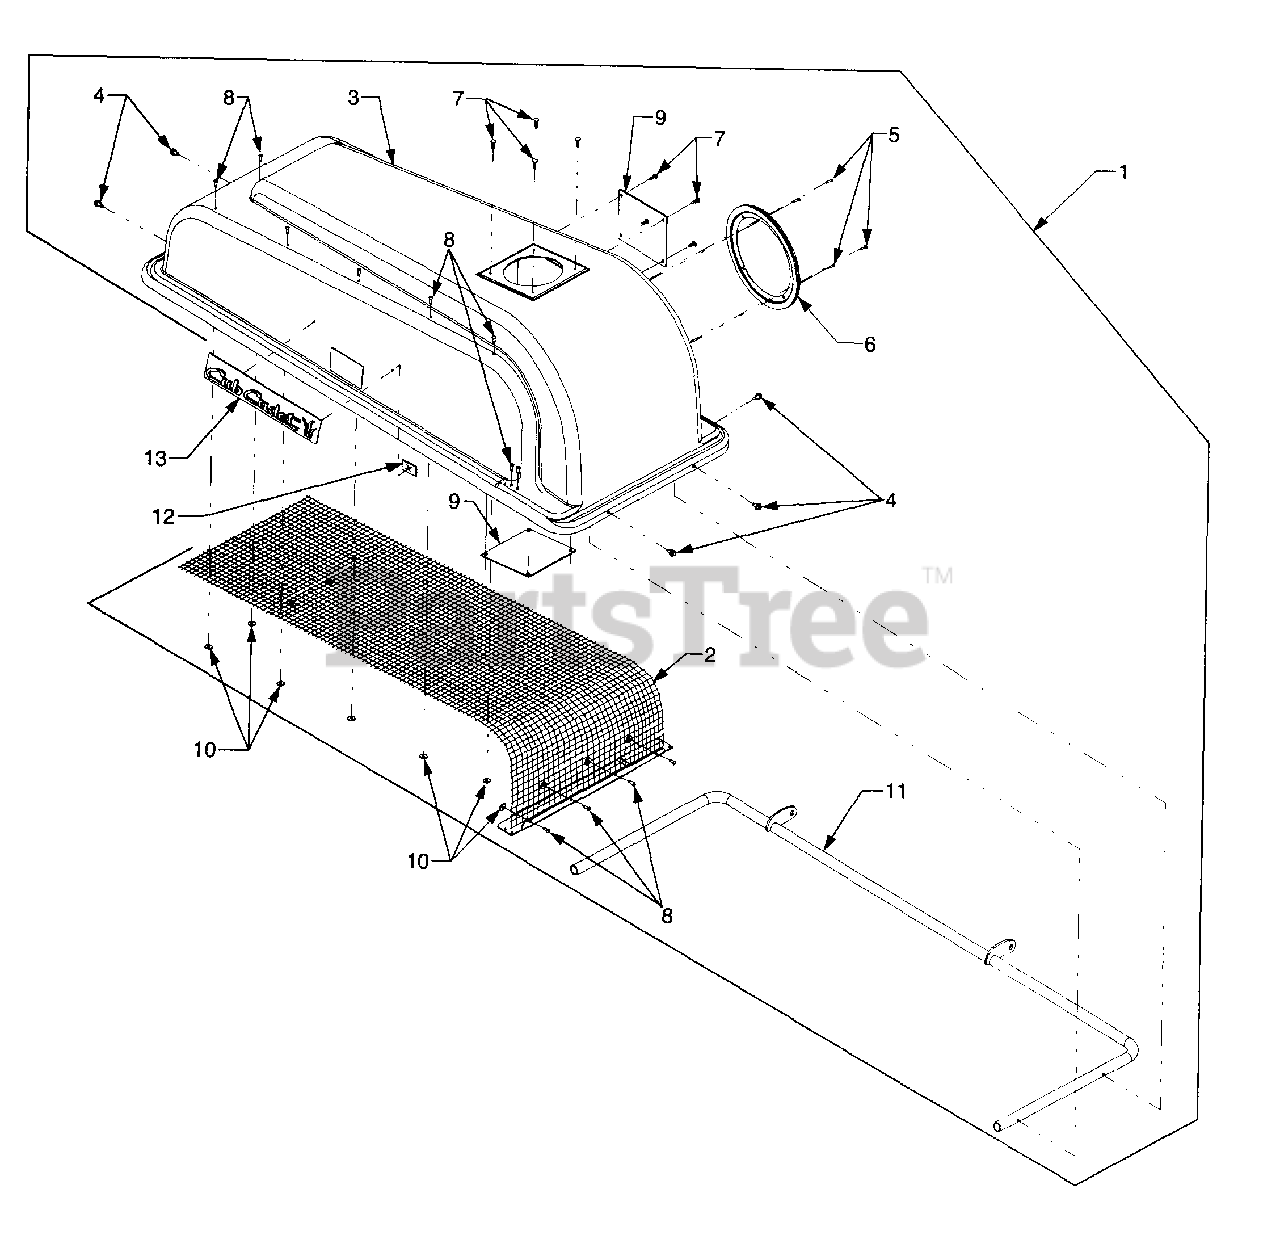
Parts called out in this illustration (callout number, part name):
1	Cover Assembly
2	Screen and Mtng. Brkt. Ass'y.
3	Cover
4	Screw, Hex Wash. Hd. Tapp 1/4-14 x .625
5	Screw, Truss Hd. Tapp 6-20 x .625
6	Seal, Tube,8.10 ID
7	Clip, Racket
8	Rivet, Pop, .187 x .45
9	Plate, Plastic
10	Washer, Flat, .194 x .62 x .063
11	Bracket Assembly, Cover Hinge
12	Speed Nut, Push On
13	Decal, Cub Cadet
